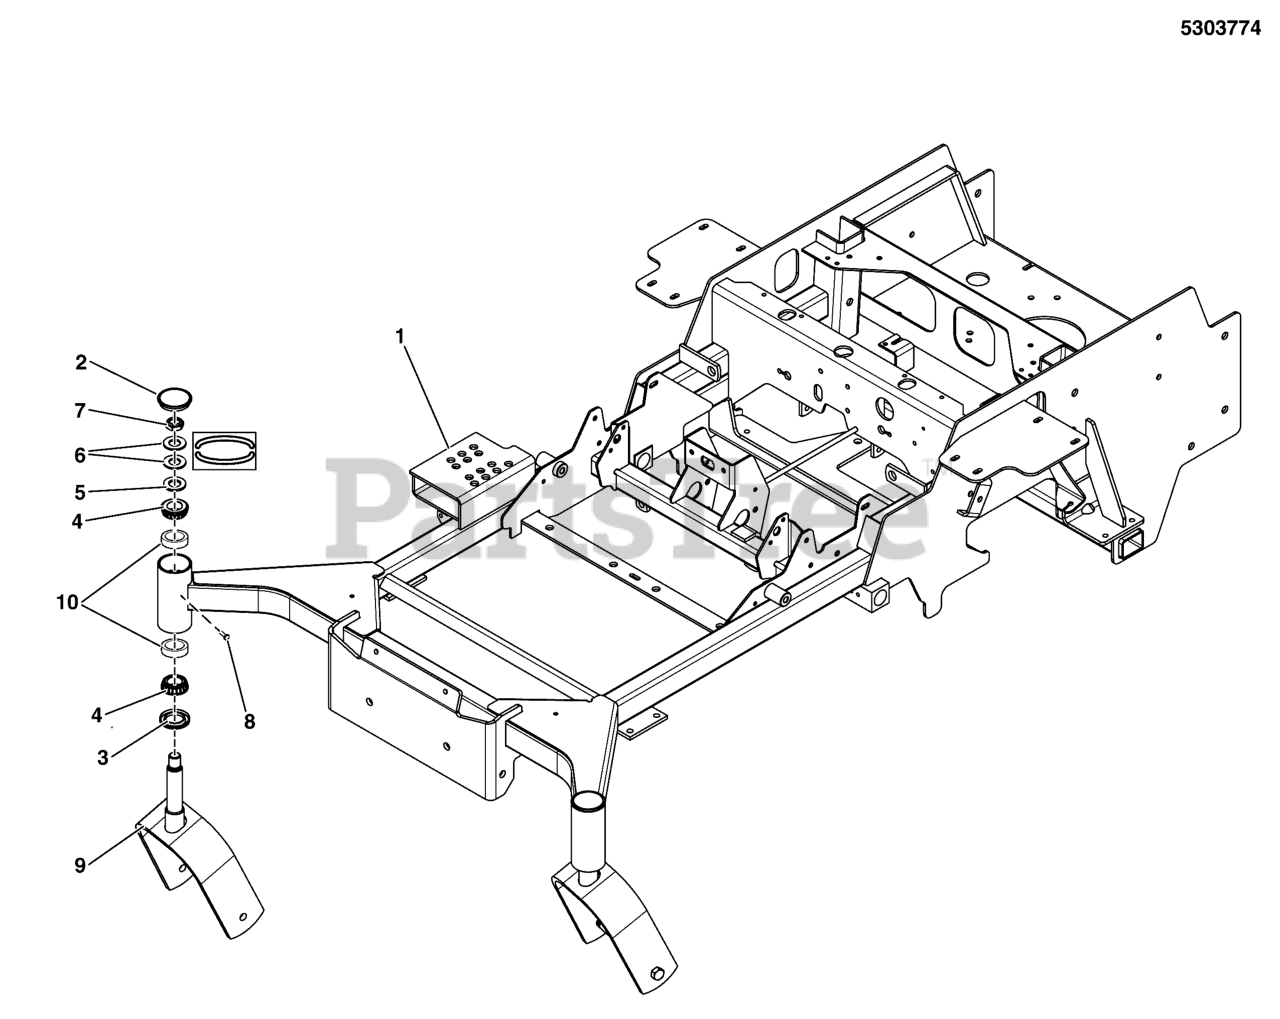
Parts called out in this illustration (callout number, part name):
1	* WELD, MAIN FRAME, F125XT - RED
2	CAP, GREASE, LOW PROFILE
3	SEAL, GREASE
4	BEARING, TAPERED ROLLER, 1
5	WASHER, 3/4 SAE
6	WASHER, BELLEVILLE - 1.500 X .755
7	NUT, 3/4-16, HEX JAM NYLON LOCK
8	BOLT, 1/4-28 X 1/2, GD5 YZ
9	WELD, CASTER YOKE - RED
10	BEARING CUP
